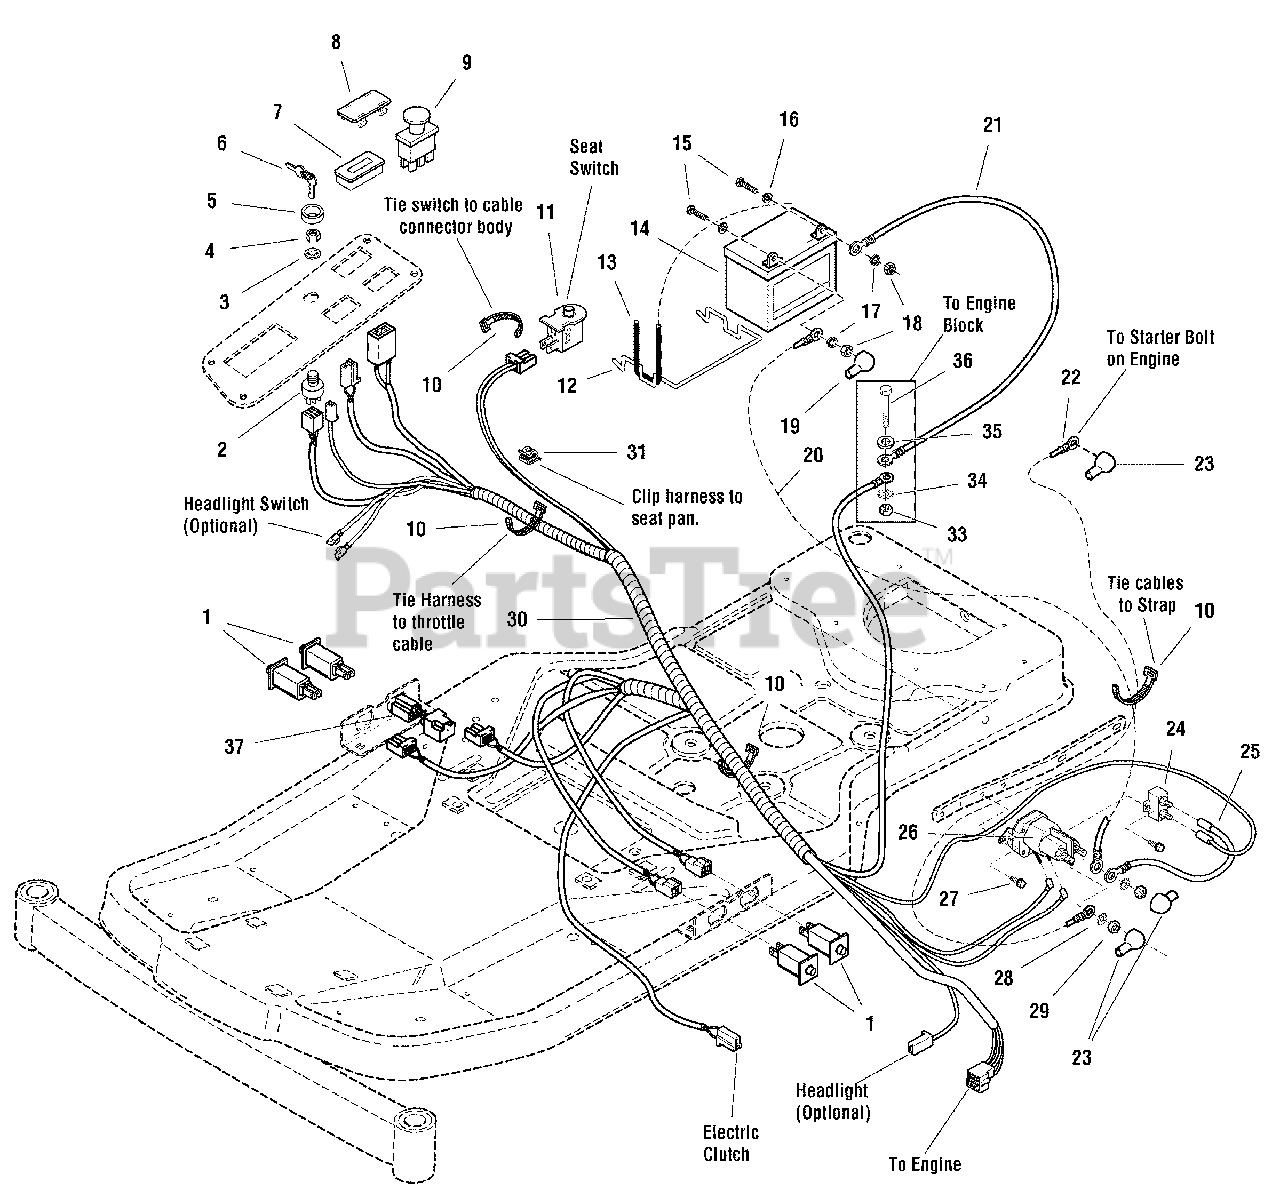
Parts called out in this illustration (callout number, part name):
1	SWITCH, Push Button
2	SWITCH ASSEMBLY, Ignition
3	LOCKWASHER, Internal Tooth, Ignition Switch
4	NUT, Hex Flange, 5/8-32, Ignition Switch
5	COVER, Ignition Switch
6	KEYS
7	METER, Hour Digital with Oil & Lube Alarms
8	PLUG, Hole
9	SWITCH, PTO, Push/Pull
10	TIE, Self Locking
11	SWITCH, Push Button, Seat Switch
12	BRACE, Battery
13	STRAP, Black
14	BATTERY, 12 Volt, 6 Cell, 340 Amps
15	CAPSCREW, Hex Head, 1/4-20 x 3/4, G5
16	WASHER, 1/4
17	LOCKWASHER, Spring, 1/4
18	NUT, Hex, 1/4-20
19	BOOT, Insulator
20	CABLE, #6 x 10, 2 Ring Terminals
21	CABLE, #6 x 15, 2 Ring Terminals
22	CABLE, #6 x 15, 2 Ring Terminals
23	COVER, Terminal
24	BREAKER, Circuit, 12 Volt, 20 Amps with Tab
25	WIRE, 12 GA
26	SOLENOID, 4 Pole, 12 Volt DC
27	CAPSCREW, Hex Washer Head Taptite, 1/4-20 x 1/2, G5
28	LOCKWASHER, External Tooth
29	NUT, Hex, 5/16-24
30	HARNESS, Wiring
31	CLIP, Cable
33	NUT, Hex Flange Whiz Lock 3/8-18
34	WASHER, External Tooth, 3/8
35	WASHER, 5/16
36	CAPSCREW, Hex Head 5/16-18 x 1-1/2, G5
37	WIRING ASSEMBLY, Jumper All Conditions Shut-Down
